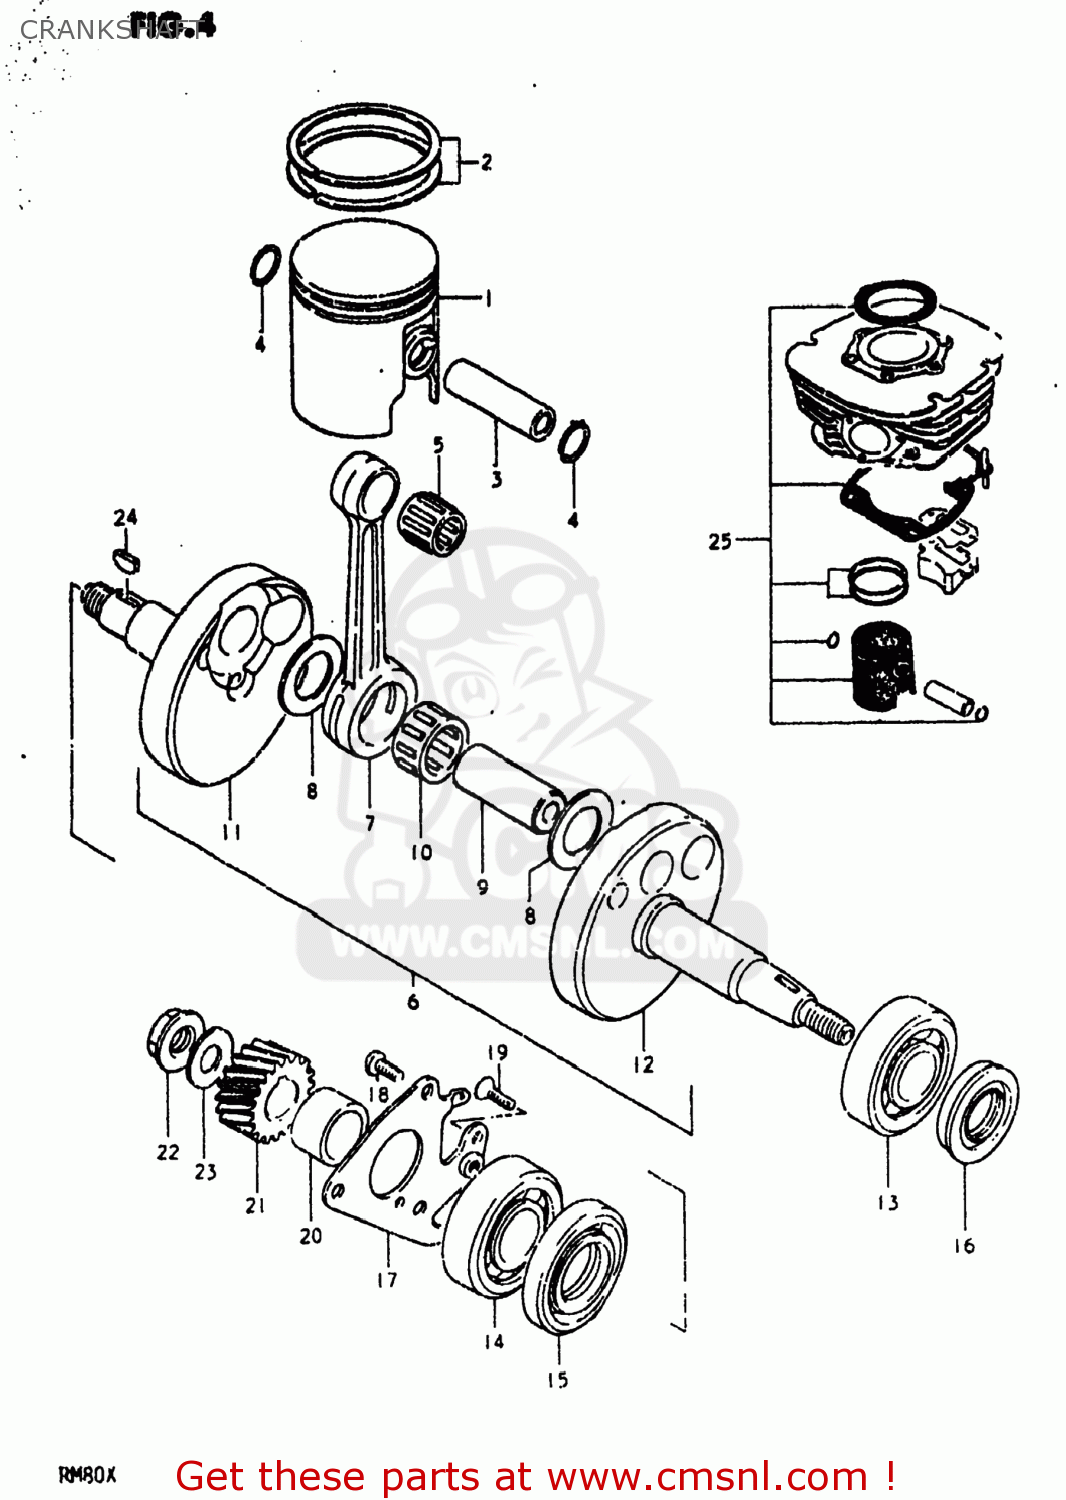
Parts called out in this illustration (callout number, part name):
1	PISTON (49.00MM)
2	RING SET,PISTON
3	PIN,PISTON
4	RING,SNAP
5	BEARING
6	CRANKSHAFT ASSEMBLY
7	ROD,CONNECTING
8	WASHER(17X29X1)
9	PIN,CRANK
10	BEARING(17X23X14)
11	CRANKSHAFT
12	CRANKSHAFT,LEFT
13	BEARING
14	BEARING
15	OIL SEAL
16	SEAL,OIL(19.6X37X8)
17	RETAINER
18	SCREW 6X12
19	SCREW
20	SPACER
21	GEAR,PRIMARY DRIVE NO.19
22	NUT
23	WASHER
24	KEY
25	PISTON SET
